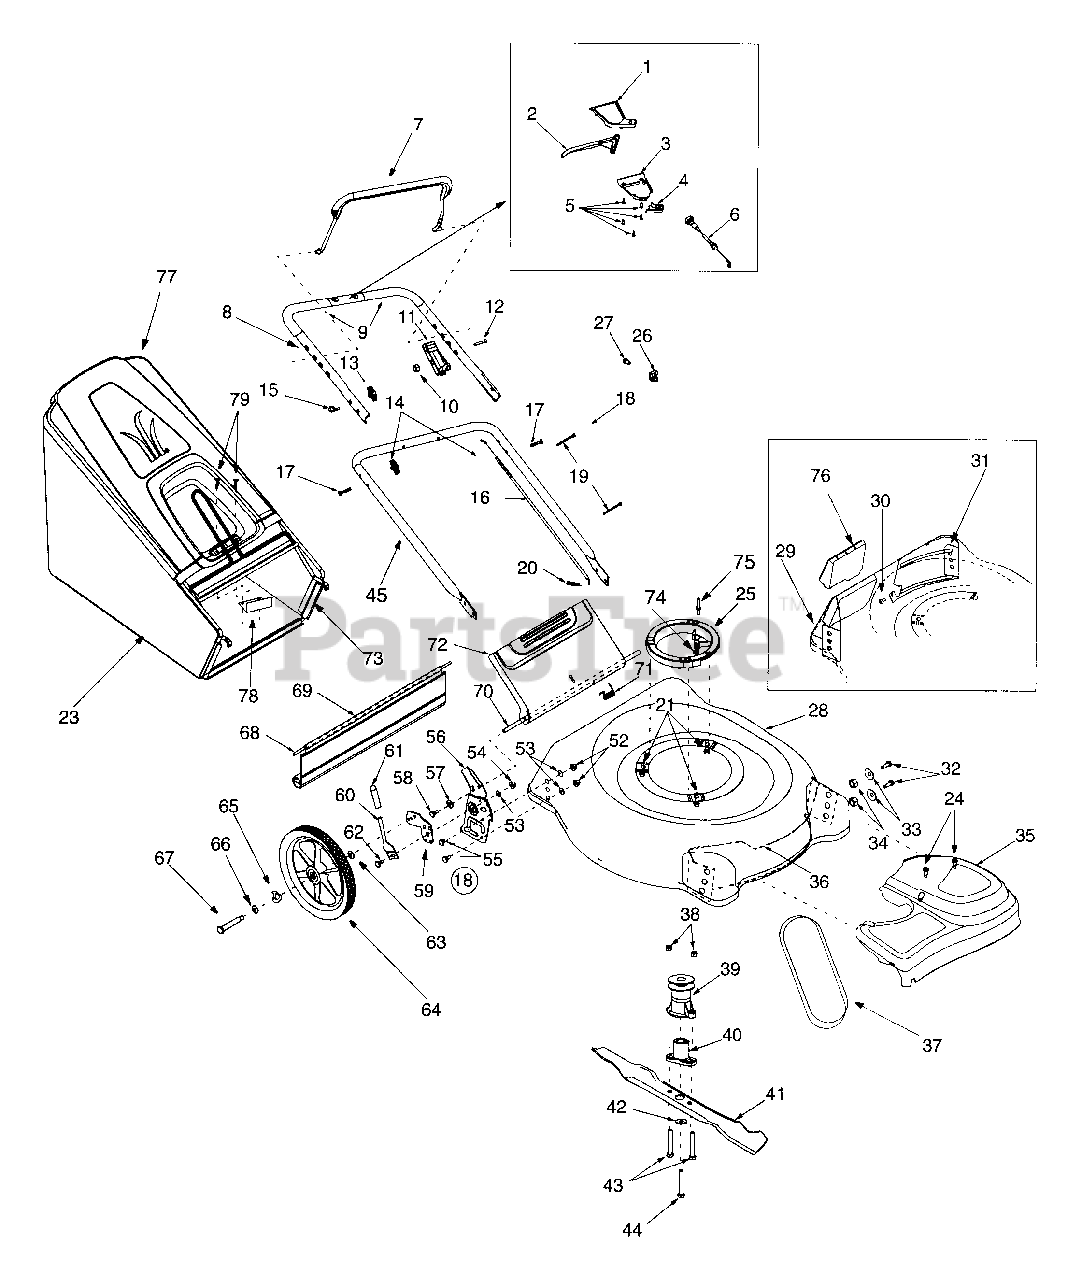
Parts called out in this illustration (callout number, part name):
1	Upper Drive Cover
2	Drive Lever
3	Lower Drive Cover
4	Mounting Cap
5	Screw # 10-12 x .75
6	Drive Cable
7	Deluxe Control Lever
9	Foam Grip, 9"
10	Hex Lock Nut, 1/4-20
11	Throttle Housing
12	Oval C-Sunk Screw 1/4-20 x 1.31
14	Handle Knob
16	Control Cable, 39"
17	Carriage Bolt 5/16-18 x 2.0
18	RH Bracket Ass'y
19	Cable Tie
21	Self-tapping Screw
23	Grassbag
24	Screw # 12 x .457
25	Engine Spacer
26	Clamp Casing
27	Hex Screw TT #10-32 x .625
30	Screw AB: 1/4-14: .625
32	Hex Screw 3/8-16 x .75
33	Bell Washer .39 x 1.13 x .062
34	Hex Nut 3/8-16
35	Transmission Cover (Black)
38	Hex Nut 1/4-20
39	Drive Pulley
40	Blade Adapter
41	21" Mulching Blade
42	Flat Washer .516 x 1.5 x .134
43	Hex Screw 1/4-20 x 1.50
44	Hex Screw 3/8-24 x 2.50
52	Hex Nut 3/8-16
53	Bell Washer .39 I.D. x 1.38 O.D.
54	Hex Flange Lock Nut 3/8-16
55	Hex Scr. w/Washer 1/4-14 x .625
57	Bell Washer .265 x .75 x .062
58	Hex Screw TT 1/4-20 x .500
59	RH Pivot Bar
60	Height Adj. Lever
62	Shoulder Scr .500 Dia. x.434
63	Washer .401 x .870 x .063
64	Wheel, 14 x 2 Gray (Link Trd.)
65	Spring Washer .50 I.D. x 1.0 O.D.
66	Flat Washer .510 x 1.373 x .04
67	Shoulder Screw
68	Wire
69	Rear Trailing Shield
71	Torsion Spring
77	Hardtop w/ logo
